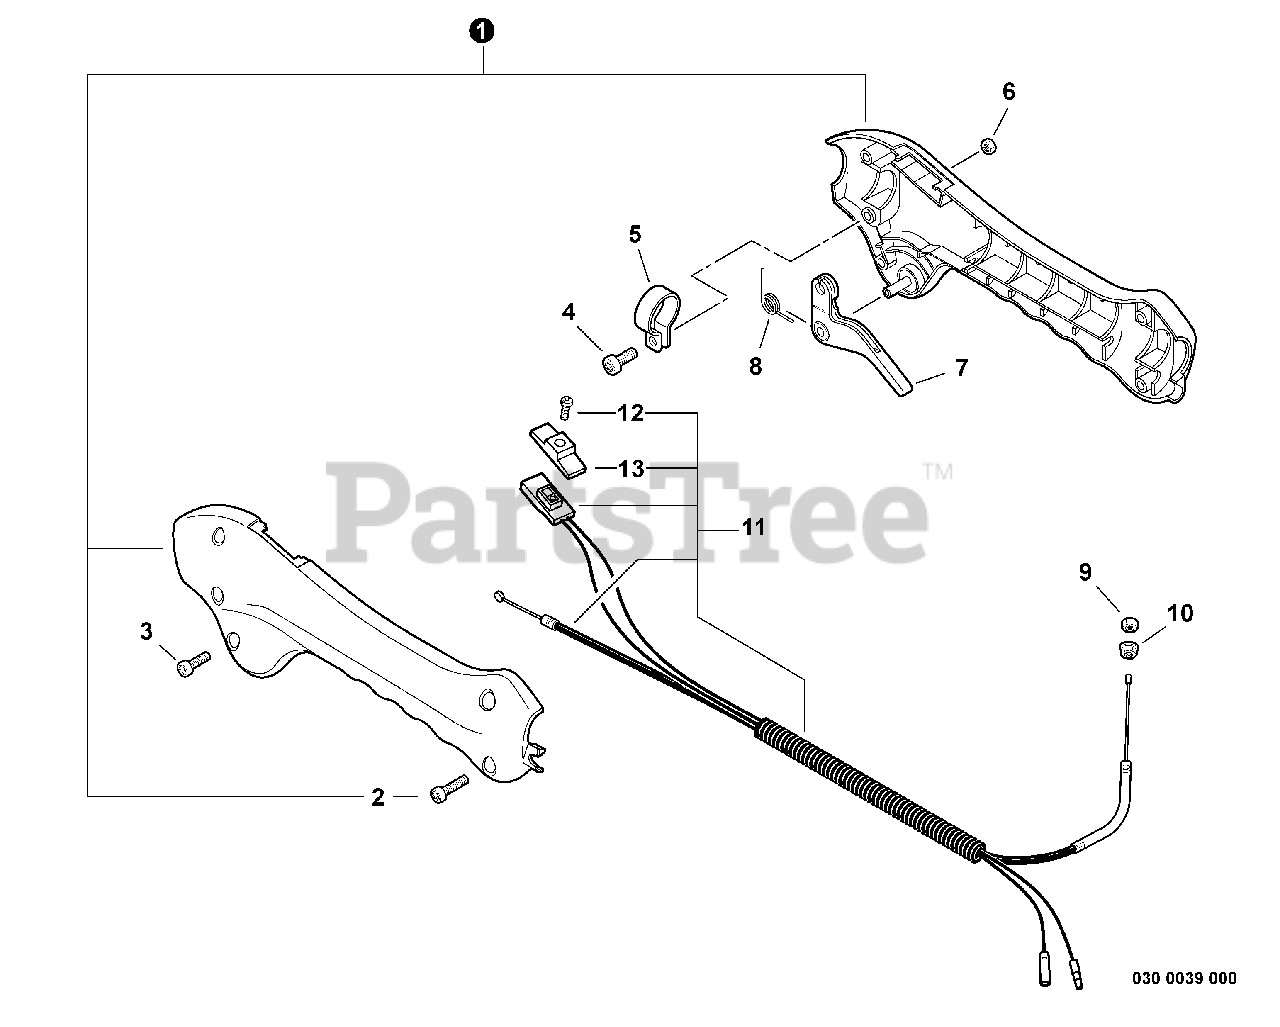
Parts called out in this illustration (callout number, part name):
1	CONTROL HANDLE ASSY
2	SCREW - 4X16 -- TAPPING
3	SCREW - 4X12
4	SCREW - 5X12
7	TRIGGER, THROTTLE
8	SPRING, TRIGGER
10	NUT - 6 -- FLANGE
11	CONTROL CABLE ASSY
12	SCREW - 3X10
13	KNOB, SWITCH - ORANGE
